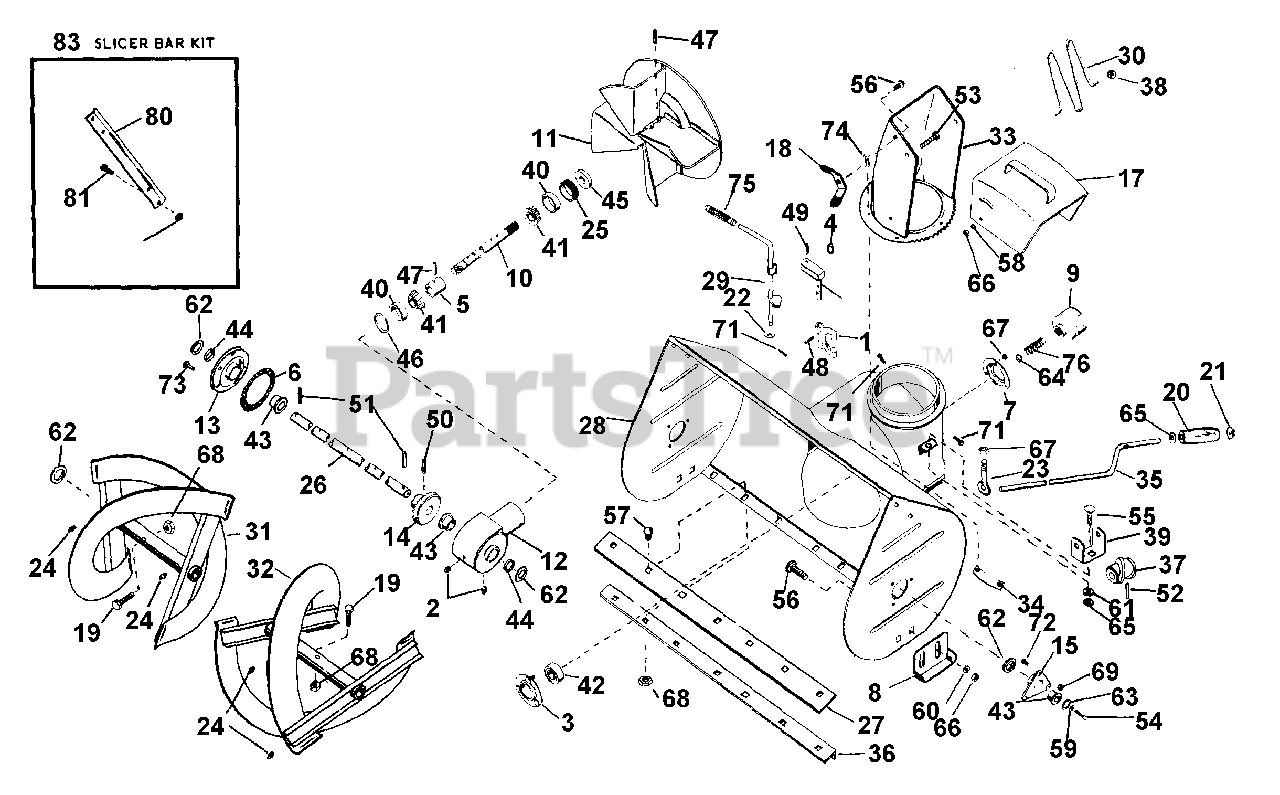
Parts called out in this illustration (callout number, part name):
1	CLUTCH FORK
2	PIPE PLUG
3	BEARING FLANGE
5	BEARING SPACER
7	BEARING FLANGE
8	RUNNER
9	JAW CLUTCH
10	HELICON PINION SHAFT
12	CASE, GEAR - C.I.
13	GEAR CASE FLANGE
14	HELICON GEAR - 41 TOOTH
15	BEARING SUPPORT
16	FORK SHAFT
17	DEFLECTOR CHUTE
18	WING NUT
19	SHEAR BOLT YWZC
21	CAP, 3/8 ROD YWZC
22	WAVE WASHER .406X.750X.063FH
23	ROD HANGER EYEBOLT
24	HYDRAULIC DRIVE FITTING
25	ADJUSTMENT PLUG
26	FRONT GEAR SHAFT
27	SCRAPER BLADE
28	BLOWER HOUSING
29	FORK CAM
30	SAFETY WIRE
31	RAKE, R.H. - 32"
32	RAKE, L.H. - 32"
33	DISCHARGE CHUTE
34	CHUTE CLAMP
36	REINFORCEMENT ANGLE
37	WORM GEAR
38	FASTENER
39	WORM CLEVIS
40	BRG-CUP 1.781X.475
41	BRG-CONE .750X.61
42	BRG-BALL .750X1.750X.50
43	BSHG-FLG 1.000X1.12X.62X1.50BR
44	SEAL 1.000X1.312X.150
45	SEAL .750X1.499X.225
46	RG-RTNG INT 1.781 HSG X.062
47	PIN-ROLL .250X1.25
48	PIN-ROLL .188X1.00
49	PIN-ROLL .313X1.25
50	PIN-ROLL .313X1.38
51	PIN-ROLL .188X1.50
52	PIN-ROLL .125X.75
53	BLT-HEX .38-16X.75 PL GR2
54	BLT-HEX .50-13X1.00 PL GR2
55	BLT-RDHDSQSHNK .31-18X.50 YZ
56	BLT-RDHDSQNK .38-16X.75 SHT PL
57	BLT-RDHDSQNK .31-18X.75 GR5 PL
58	WSHR-LK .375X.115 HVY PL
59	WSHR-LK .500X.151 HVY PL
60	WSHR-FL-STL .38X.875X.083 PL
61	WSHR-FL-STL.312X.734X.065PL
62	WSHR-FL-STL 1.010X1.505X.062PL
63	WSHR-FL-STL .511X1.441X.125 PL
64	WSHR-FL-STL .755X1.375X.062 PL
65	WSHR-FL-STL .382X.812X.023 PL
66	NUT-LK-CTR .375-16 GR A PL
67	NUT-LK-CTR .250-20 PL
68	NUT-LK .312-18 GR A PL
69	NUT-LK-FLG .250-20 PL
70	PIN-COTR .12X1.0 PL
71	BLT-SCRHFWH .38-16X.50 PL
72	SCR-SLTR-SERNK .25-20X.62 PL
73	BLT-SERHFWH .25-20X.75 PL
74	SCR-TAP 10-24X.375 CRPH 1A
76	SG-COMP .105X1.35X1.984
77	SNO-THRO DECAL
78	CAUTION LABEL
79	CLUTCH INSTRUCTION DECAL
80	CUTTER BAR
81	BLT-RDHDSQSHNK .31-18X.50 YZ
82	NUT-LK .312-18 GR A PL
83	SLICER BAR KIT
